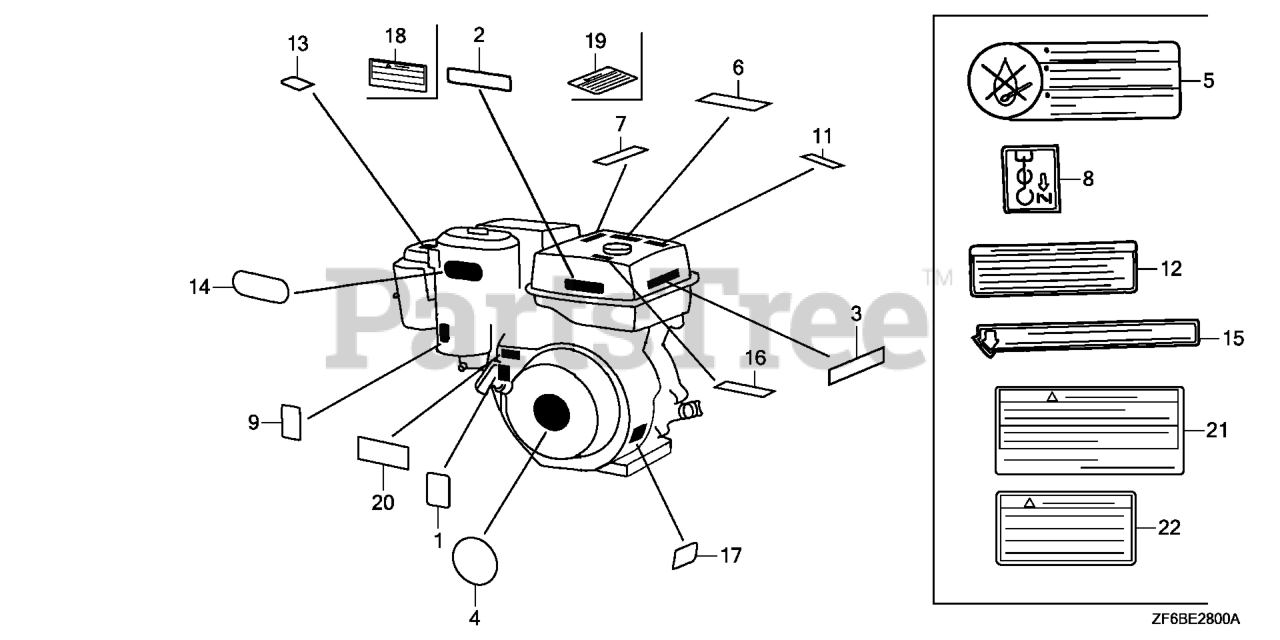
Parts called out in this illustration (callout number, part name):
1	LABEL, WARNING (NOT CERTIFIED FOR SALE)
4	EMBLEM (GX39 (HONDA)
9	MARK, CHOKE
18	MARK, OPERATOR CAUTION (ENGLISH)(MADE IN JAPAN)
19	MARK, EX. CAUTION (ENGLISH)
20	MARK, THROTTLE INDICATION
21	MARK, OPERATOR CAUTION (FRENCH)(MADE IN JAPAN)
22	MARK, EX. CAUTION (FRENCH)
